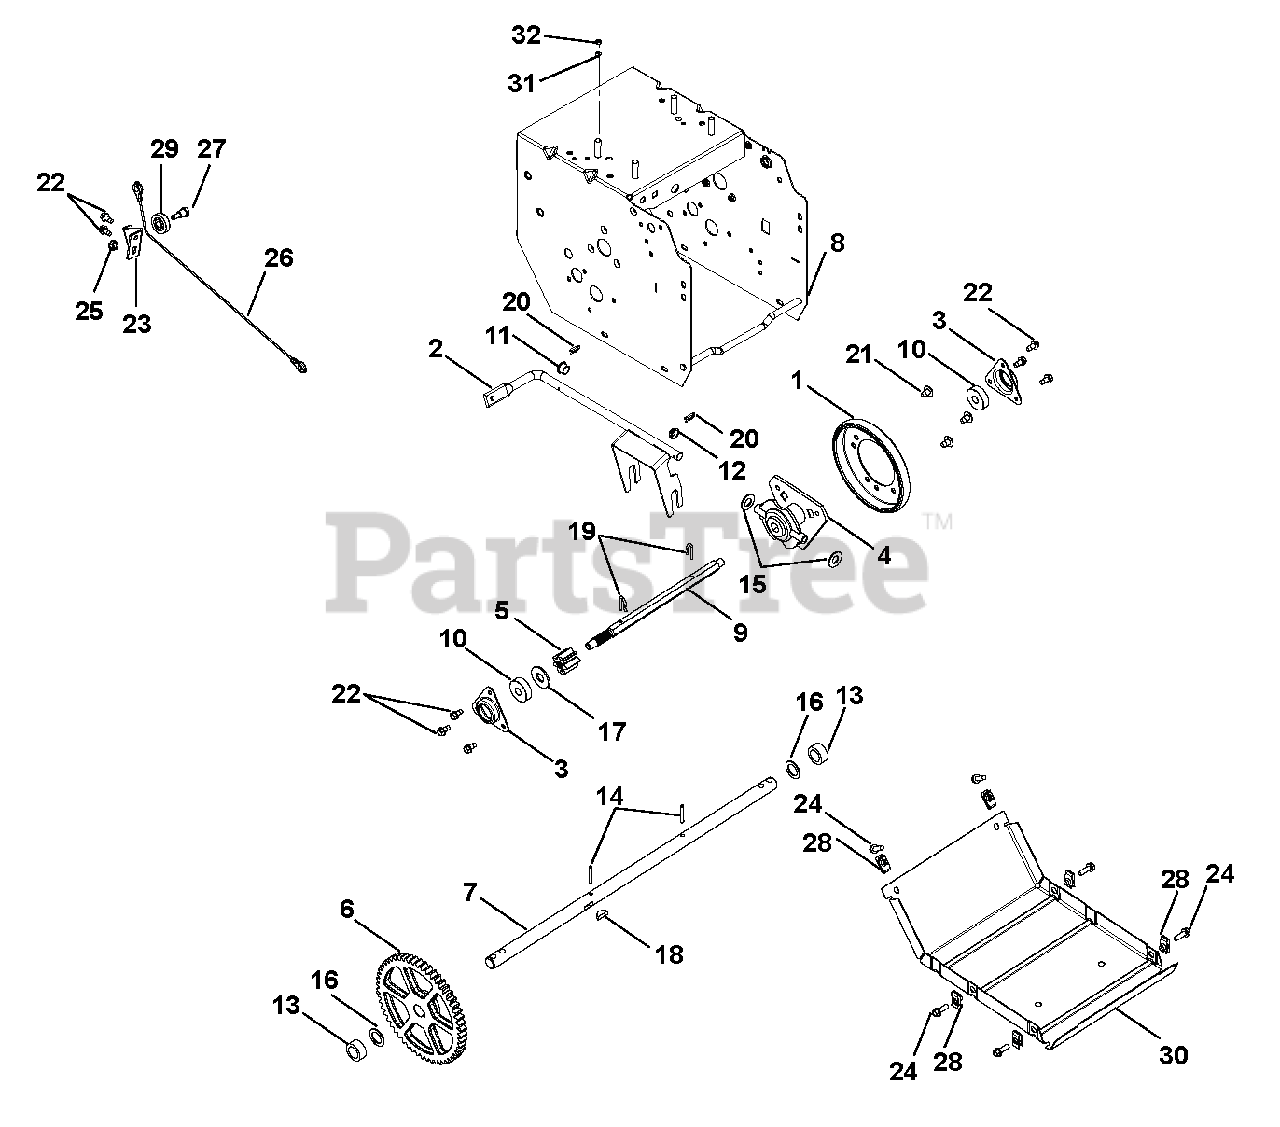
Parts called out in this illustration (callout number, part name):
1	FRICTION, DISC
2	WELDMENT, SHIFT FORK
3	FLANGE, BEARING
4	CARRIER, DRIVE DISK
5	GEAR, PINION, 7 TOOTH W/SPLINE
6	SPUR GEAR, 54T .75ID X 6.75PD
7	AXLE, COMPACT 920,XXX 15" TIRE
8	FRAME W/ENGINE BOLT STRAPS
9	SHAFT, HEX W/SPLINE
10	BRG-BALL .437X1.375X.437
11	BUSHING, POLYLINER-.50 SPLIT
12	BUSHING, POLYLINER-.50 SNAPIN
13	BSHG-SLV .766 X 1.125 X .500
14	PIN-ROLL .188X1.25
15	WSHR-FL-STL .505X1.00X.062YWZC
16	WSHR-FL-STL.754X1.125X.062YWZC
17	@WSHR-FL-STL.563X1.38X.109YWZC
18	KEY-WDRF .25X.750X.313 SAE91
19	PIN, SPRING CLIP
20	CLIP, SPRING
21	SCR-TAP SERRDHDTX .31-18X.50BP
22	SCR-TAP .25-20X.50 HWH TR YWZ
23	BRACKET, CABLE PULLEY
24	BLT-HEX .25-20X.75 HWH YZ GR5
25	@NUT-LK-CTR-FLG .25-20 YWZC
26	CABLE, LOWER TRACTION (CMPCT)
27	BOLT, SHLDR-.375X.375X.25-20
28	NUT-RTNR .25-20X.56
29	PULLEY, CABLE
30	COVER, BOTTOM
31	WSHR-LK .312X.097 HVY YWZC
32	@NUT-HEX .31-18 YWZC
